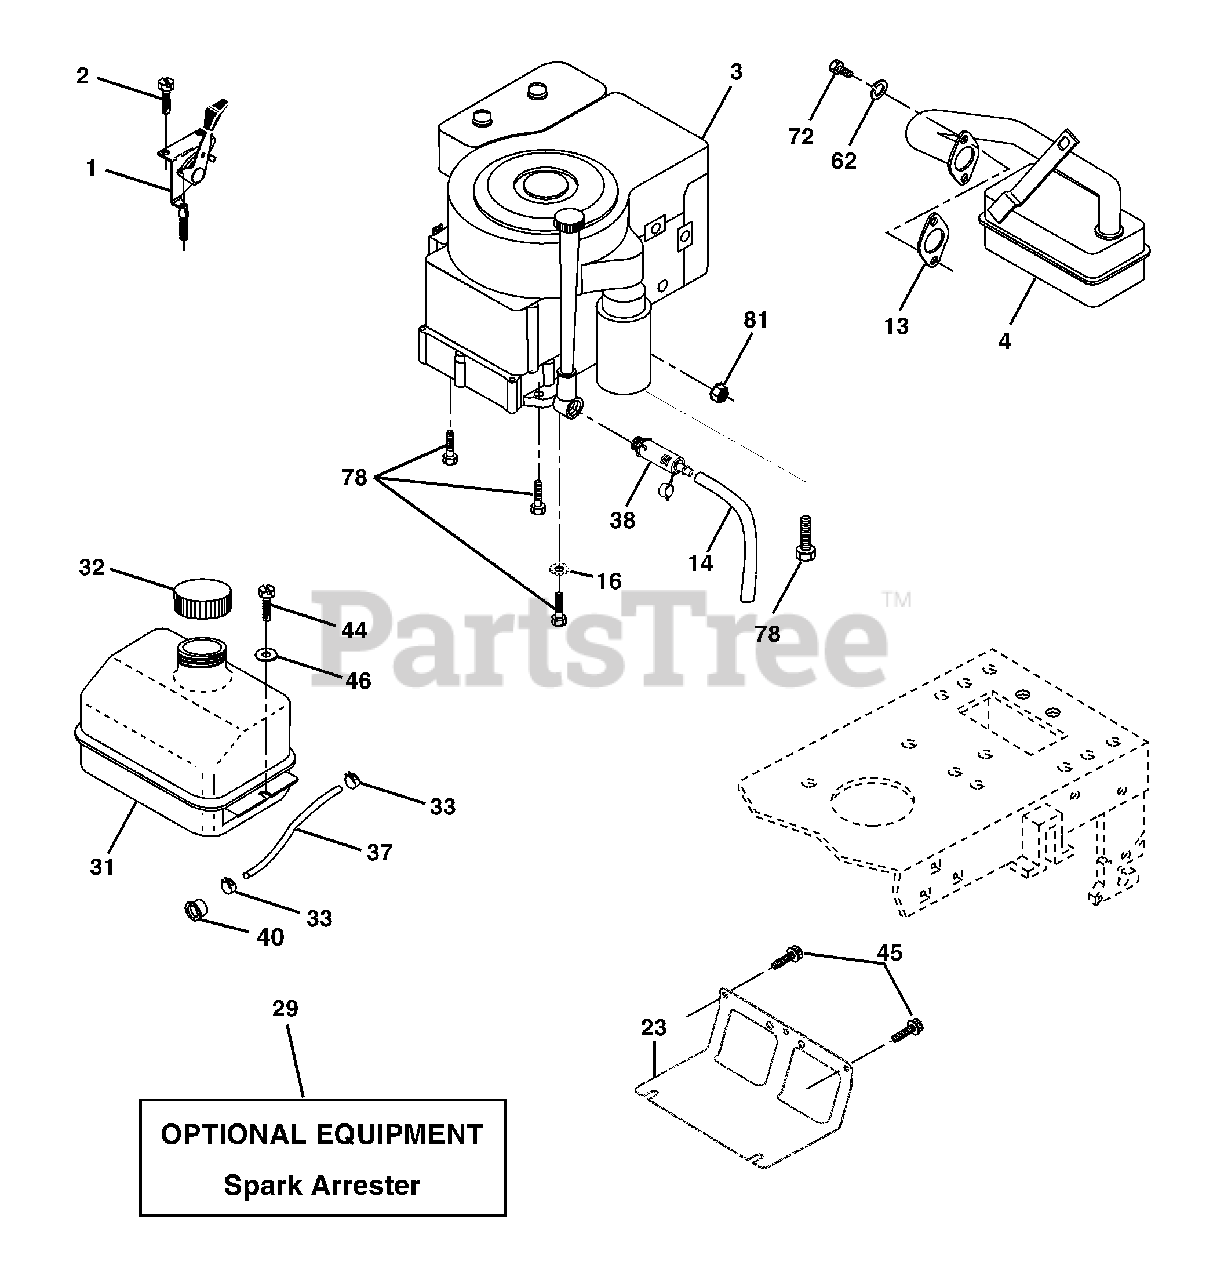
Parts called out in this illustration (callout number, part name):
1	Control Throt /Ch Flag
2	Screw Hex Thd Cut 1/4-20x1/2
4	Muffler Exhaust B&S Lt
13	Gasket 1 313 Id Tin Plated
14	Tube Drain Oil Easy
16	Washer Lock Ext Tooth 3/8
23	Shield Browning/Debris Guard
29	Arrestor Spark
31	Tank Fuel 1 25 Fr
32	Cap Asm Fuel W/sym Vented
33	Clamp Hose Blk
37	Line Fuel 20"
38	Plug Drain Oil Easy
40	Bushing Snap Nyl Blk Fuel Line
44	Screw Hexwsh Thdrol 1/4-20x3/4
45	Screw Hex Wsh Thdrol 3/8-16
46	Washer 9/32 X 7/8 X 16ga
72	Screw Socket Head 5/16-18 x 1
78	Screw 3/8-16x1-1/4
81	Nut Keps Hex 1/4-20 Unc
